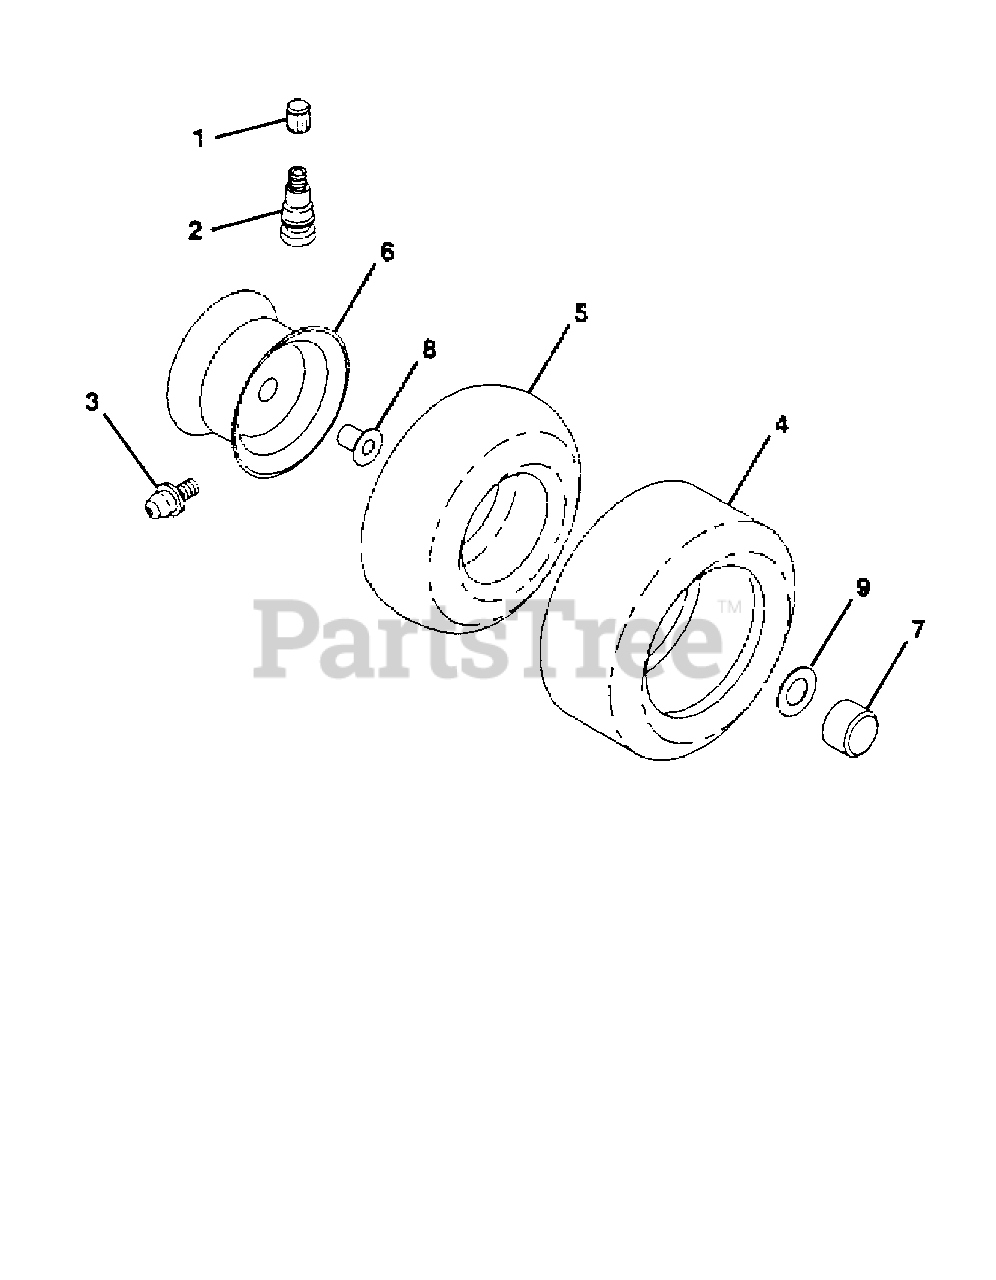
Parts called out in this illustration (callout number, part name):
1	VALVE CAP
2	VALVE STEM LT
3	FITTING LT
4	TIRE HEAVY DUTY
4	Tire, .23 X 8.5-12 Turf Saver
5	TUBE.5.3/4.5/6
5	TUBE.23"X9.5""X12""
6	RIM.ASM.6".FRONT.SILVER
7	CAP.HUB.FRONT.LT.BLACK
8	BEARING T
